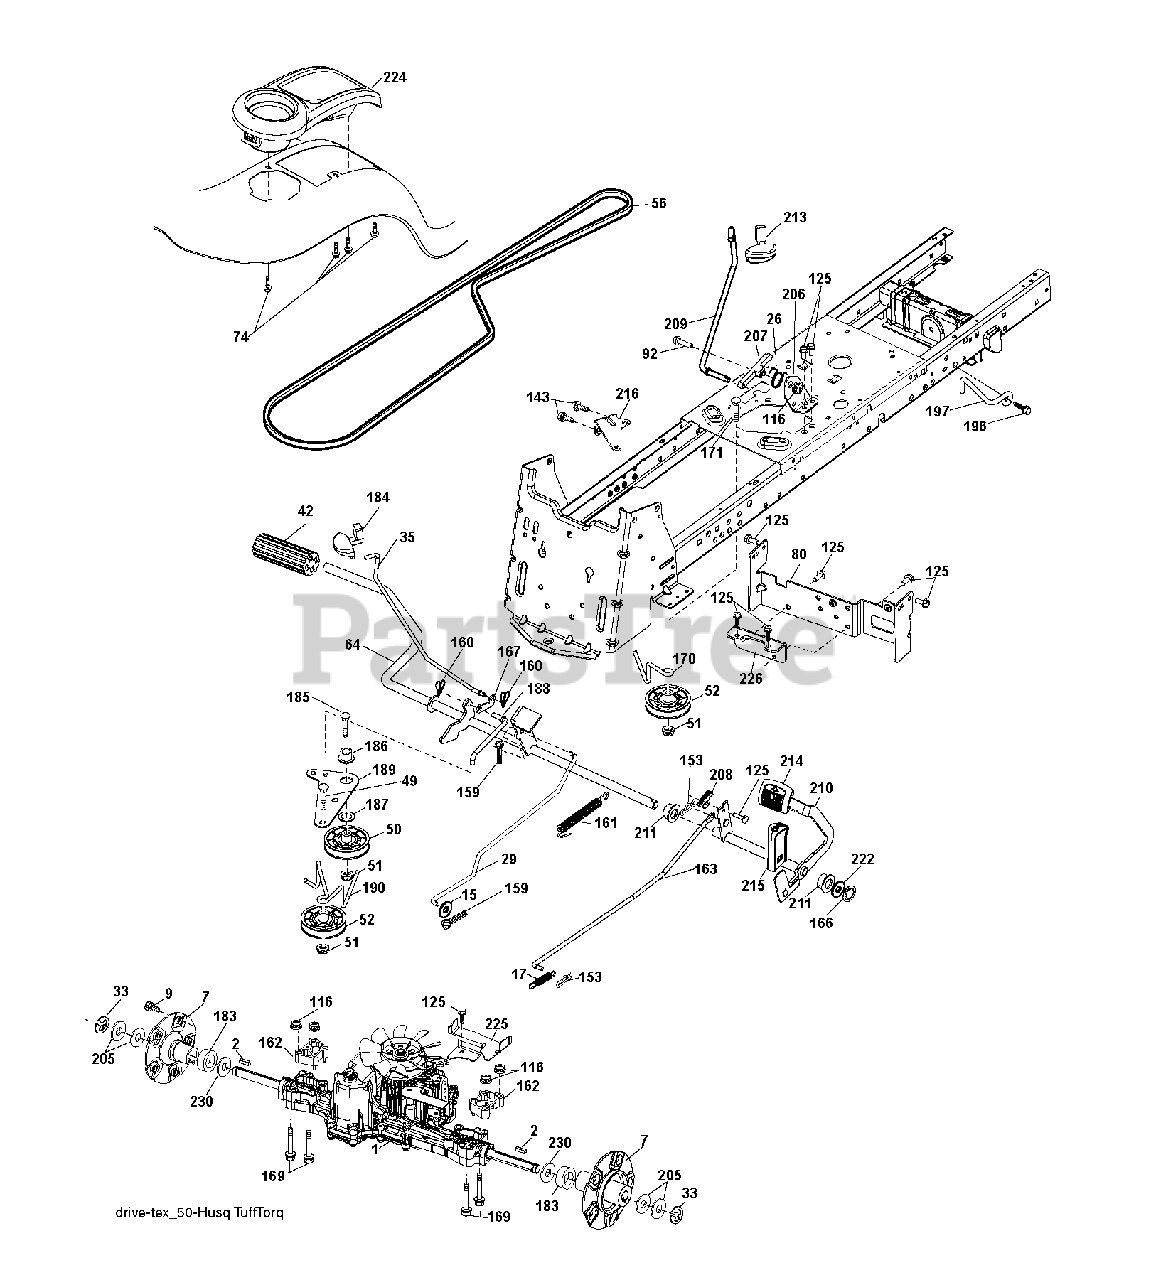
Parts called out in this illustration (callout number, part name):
1	TRANSAXLE.K46BN.PEDAL CONTROL
2	KEY.SQUARE.187X2.500
7	HUB.ASM.WHEEL.REAR.22"
17	SPRING.BRAKE.K46.GREEN
26	SPRING.RETURN.CRUISE
29	ROD.BRAKE.K46
33	E-RING LT
35	ROD.BRKAE.PARKING.STEALTH
42	PEDAL COVER T
49	BOLT
50	IDLER.FLAT.910.OFFSET
51	NUT LOCK FLG 3/8-16 UNC
52	IDLER.V-GROOVE.910.OFFSET
64	SHAFT.ASM.PEDAL.BRK.CNTR
74	SCREW.HI-LO.CONSOLE
80	STRAP.TORQUE.HG3000/K46
92	BOLT
116	NUT LOCK HEX FLANGE 5/16-18
125	SCREW
153	RETAINER M
159	COTTER PIN
160	RETAINER CLIP
161	SPRING.RETURN.CLUTCH.2006
162	SPACER.TRANSAXLE.18&22
163	ROD.CONTROL.PEDAL.K46
166	NUT.PUSH.625.2006
167	LATCH.BRAKE.SPRING
169	BOLT.HEX.FLNG.5/16-18X3.75
170	KEEPER.V-IDLER.CENTER.
171	BOLT
183	SPACER.SPLIT.800X.350
184	HANDLE.PRKG.BRAKE.STLTH.TX.RED
186	SPACER.RETAINER
187	WASHER 12/32X2X10GA
188	LINK.CLUTCH.GROUND.DRIVE
189	BELLCRANK.GROUND.DRIVE.TEX.
190	KEEPER.BELLCRANK.DRIVE
196	SCREW 3/8-16X1
197	BRKT.ANIT-ROTATION.CLU
206	BRKT.MOUNT.LATCH.CRUIS
207	LATCH.CONTROL.CRUISE
208	GEAR.SECTOR.CONTROL.CR
209	ROD.CONTROL.CRUISE.STEALTH.TEX
210	ROCKER.ASM.PEDAL.CONTR
211	BEARING.NYLON
213	KNOB.CONTROL.CRUISE
214	PEDAL.FORWARD.TEX.GT.4
215	PEDAL.REVERSE.TEX.GT.4
216	BRACKET.PULLEY.IDLER.W/TEX
222	WASHER 21/32 X 1-1/4 X 10 GA.
224	CONSOLE.TOOLBOX.PCH.ERGO.BLACK
225	KEEPER.BELT.TRANSAXLE.K46
226	BRKT.MOUNT.TORQUE.K46.
230	WASHER.HARDENED
